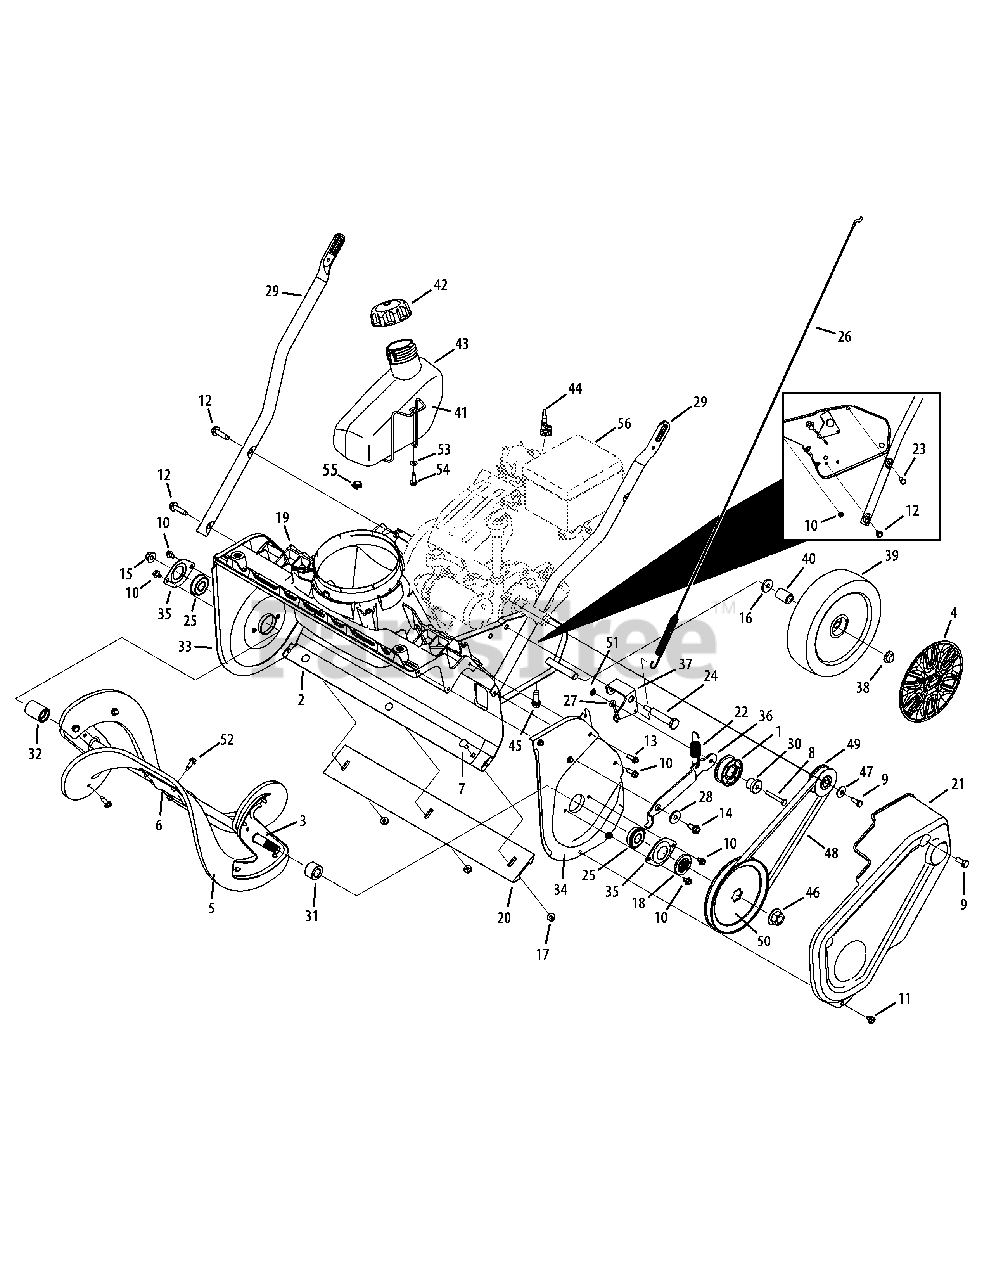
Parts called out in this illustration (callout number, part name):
1	Idler Pulley Assembly
2	Frame
3	Auger Assembly Mount
5	Auger Replacement Kit
6	Center Auger Bracket
7	Carriage Screw, 1/4-20 x .62
8	Hex Screw, 1/4-20 x 1.50
9	Hex Lock Screw, 5/16-24 x .875
10	Hex Washer Screw, 1/4-20 x .750
11	Hex Washer Screw, 1/4-20 x .500
12	Hex Washer Screw, 5/16-18 x 1.250
13	Hex Washer Screw, 1/4-15 x .750
14	Hex Washer Screw, 5/16-18 x .75
15	Flange Lock Nut, 3/8-16
16	Flat Washer, .535 x .930 x .090
17	Flange Lock Nut, 1/4-20
18	Pulley Hub
19	Chute Adapter
20	Shave Plate
22	Extension Spring, .70 x 3.035
23	Hex Screw, 5/16-24 x 1.25
24	Shoulder Bolt, 5/16-24 x .496 x 2.18
25	Ball Bearing, .500 x 40mm x 12mm
26	Clutch Cable
27	Drive Cable Wire Support
28	Shoulder Spacer
30	Shoulder Spacer, .260 x .785 x .538
31	LH Auger Spacer
32	RH Auger Spacer
33	RH Auger Plate
34	LH Auger Plate
36	Idler Bracket
37	Cable Idler Bracket
38	Push Cap, 1/2
40	Sleeve Spacer, .525 x .775 x .835
41	Gas Tank Wire Support
42	Fuel Cap
43	Fuel Tank
44	Choke Extension Lever
45	Hex Washer Screw, 3/8-16 x 1.000
46	Flange Nut, 7/16-20
47	Thrust Washer, .330 x 1.25 x .120
48	Belt, .500 x 35.06
49	Pulley Half, .625 x 2.25
50	Pulley, 1/2 x 6.00
52	Hex Washer Screw, 1/4-20 x .750
53	Washer, .265 x 1.00 x .030
54	Screw, 1/4-10 x .625
55	Hose Clamp
56	Replacement Engine
